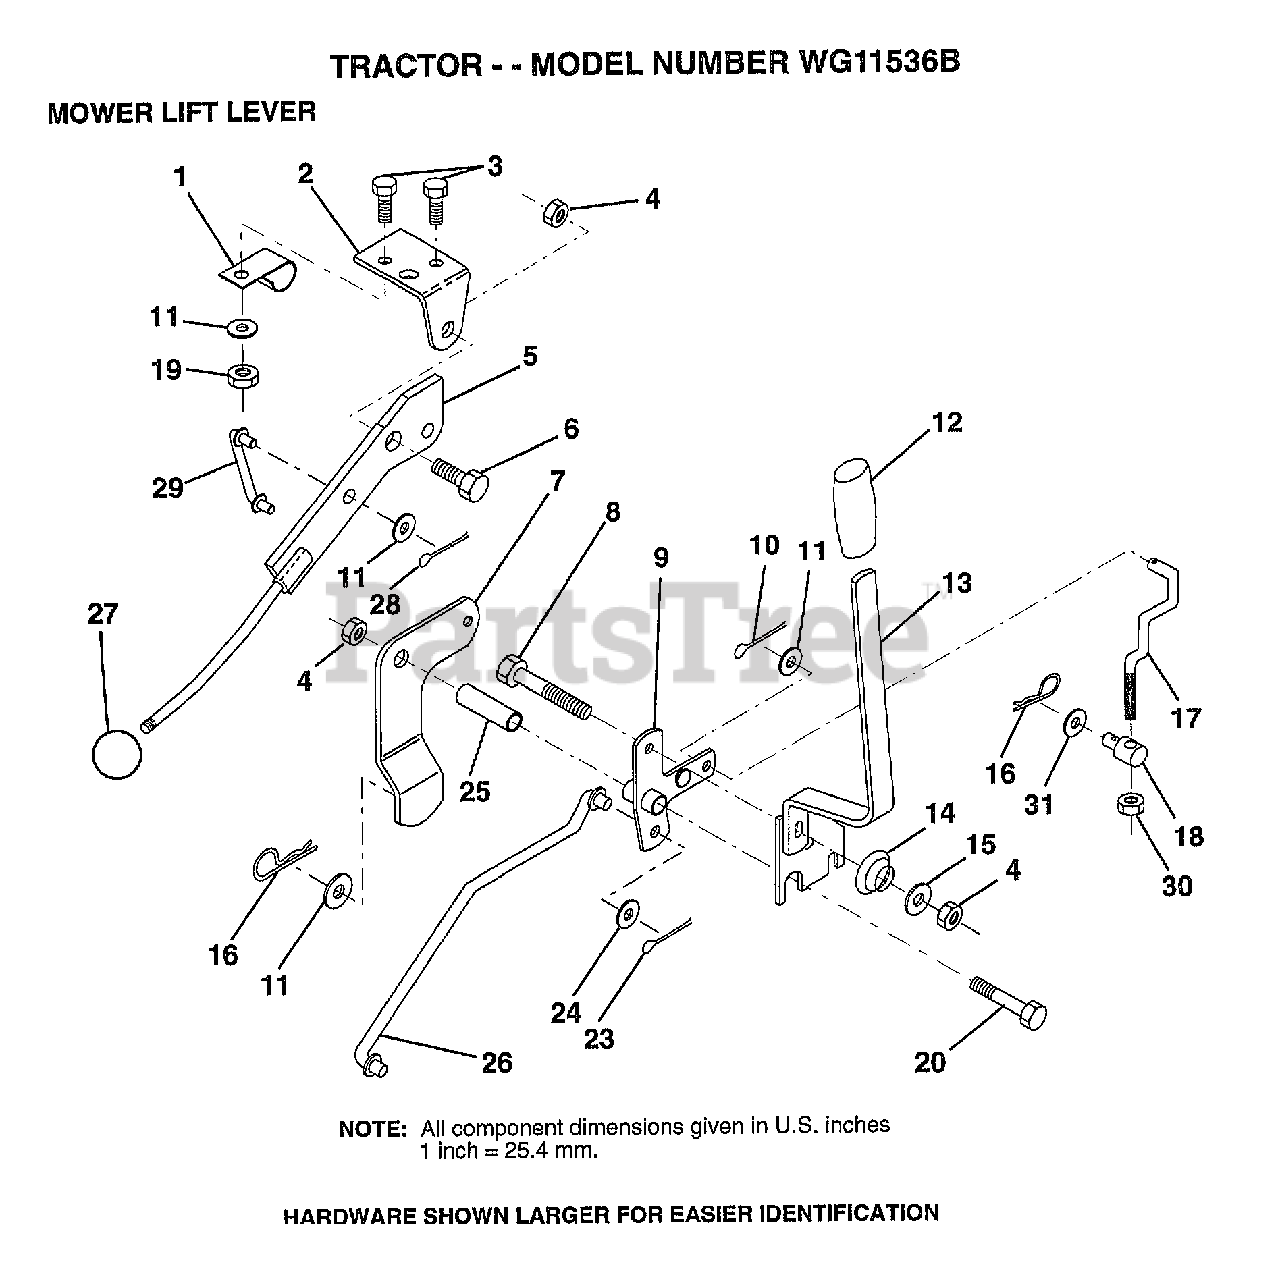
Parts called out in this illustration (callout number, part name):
1	"CLIP,INSULATOR"
2	BRKT CLUTCH
3	BOLT HXHD FIN
5	LEVER.ASM.CLUTCH
6	"BOLT, SHOULDER LT"
7	MWR CLUTCH ARM AS
8	BOLT
9	"BELLCRANK,LIFT"
10	COTTER PIN
11	WASHER
13	HANDLE.ASM.LIFT
14	SPRING COMPRESSIO
15	WASHER T
17	"LINK,LIFT FRT"
18	TRUNION ADJ
20	BOLT
23	PIN COTTER 1/8
25	TUBE SPACER
26	ROD LIFT MOWER
27	KNOB T(3/8 HOLE)
29	CLUTCH LINK
30	NUT
31	WASHER
